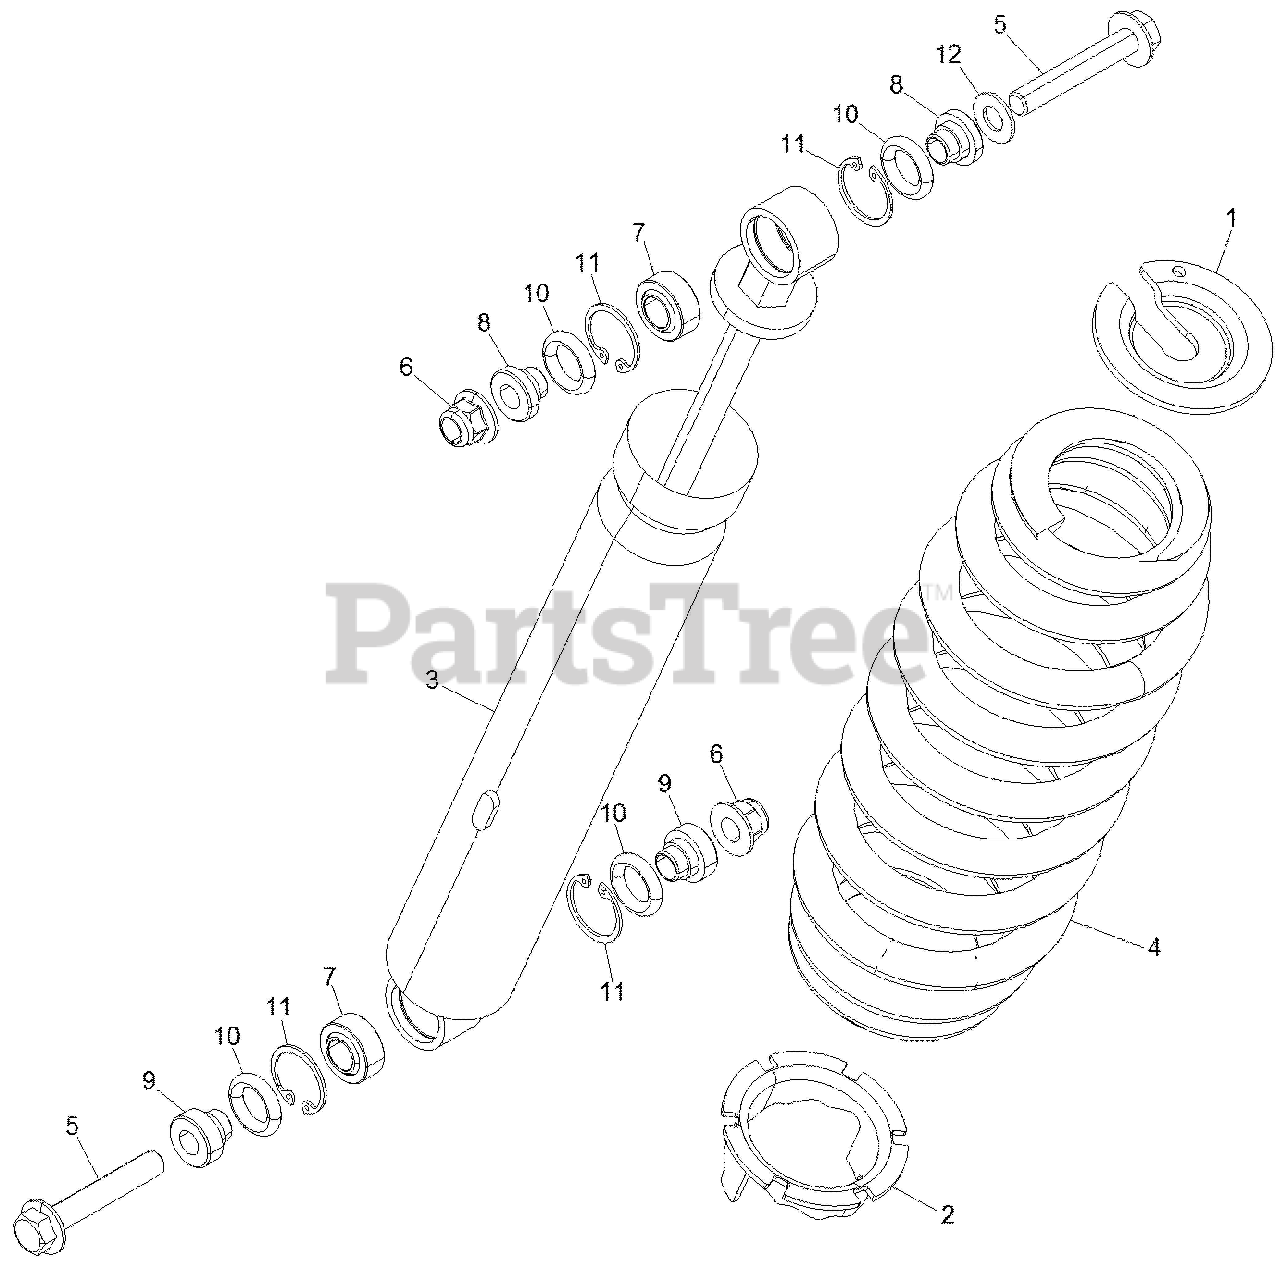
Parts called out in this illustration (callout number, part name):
1	RETAINER-SPRING,STEEL
2	CAM-ADJUSTING,SPRING,STEEL
3	SHOCK-REAR
4	SPRING, REAR, MATTE BLACK
5	SCR-HXFL-M10X1.25X60 10.9 ZOD
6	NUT-M10X1.25,FLG,NYLOC-OLIVE D
7	BEARING-SPERICAL,SHOCK
8	BUSHING, REDUCER
9	BUSHING-REDUCER,10MM WIDE,ZYW
10	O-RING,0.600IDX.210
11	RING-RETAINING,1.00 ID
12	WASHER,3/8 FW
